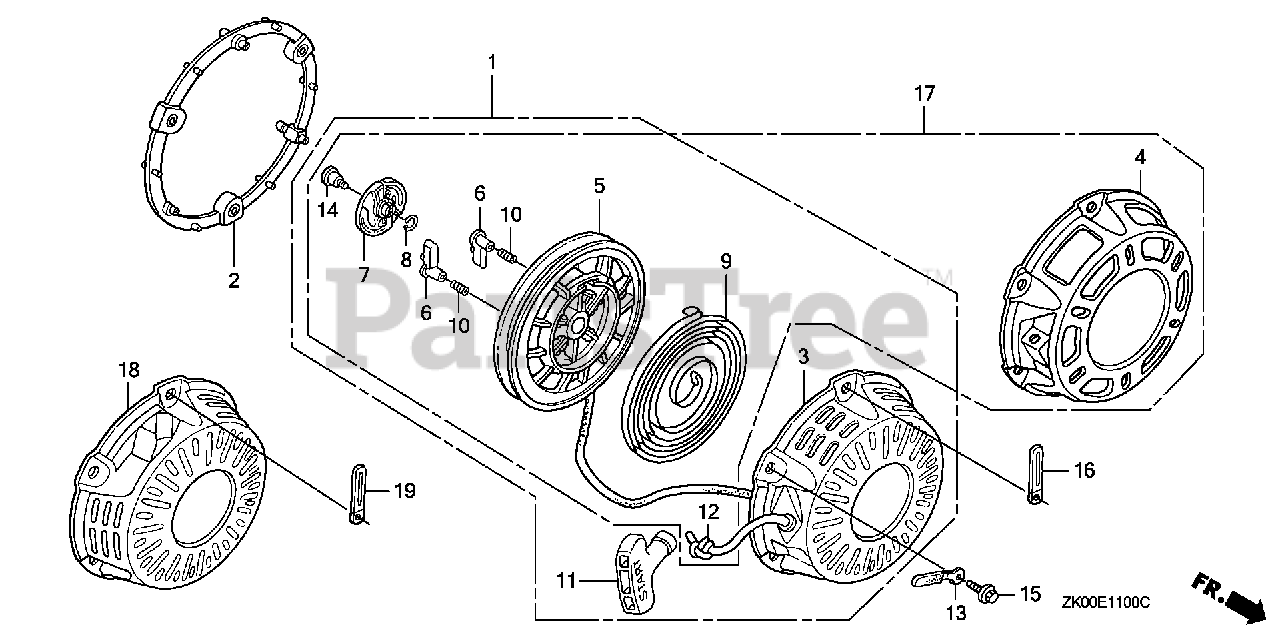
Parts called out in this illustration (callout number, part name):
1	STARTER ASSY., RECOIL *R280* (POWER RED)
2	SPACER, RECOIL STARTER MOUNTING *R280* (POWER RED)
3	CASE, RECOIL STARTER *R280* (POWER RED)
5	REEL, RECOIL STARTER (NATURAL)
6	RATCHET, STARTER
7	GUIDE, RATCHET
8	SPRING, FRICTION
9	SPRING, RECOIL STARTER
10	SPRING, RETURN
11	GRIP, STARTER
11	KNOB, RECOIL SRARTER
12	ROPE, RECOIL STARTER
14	SCREW, SETTING
15	BOLT, FLANGE (6X18)
